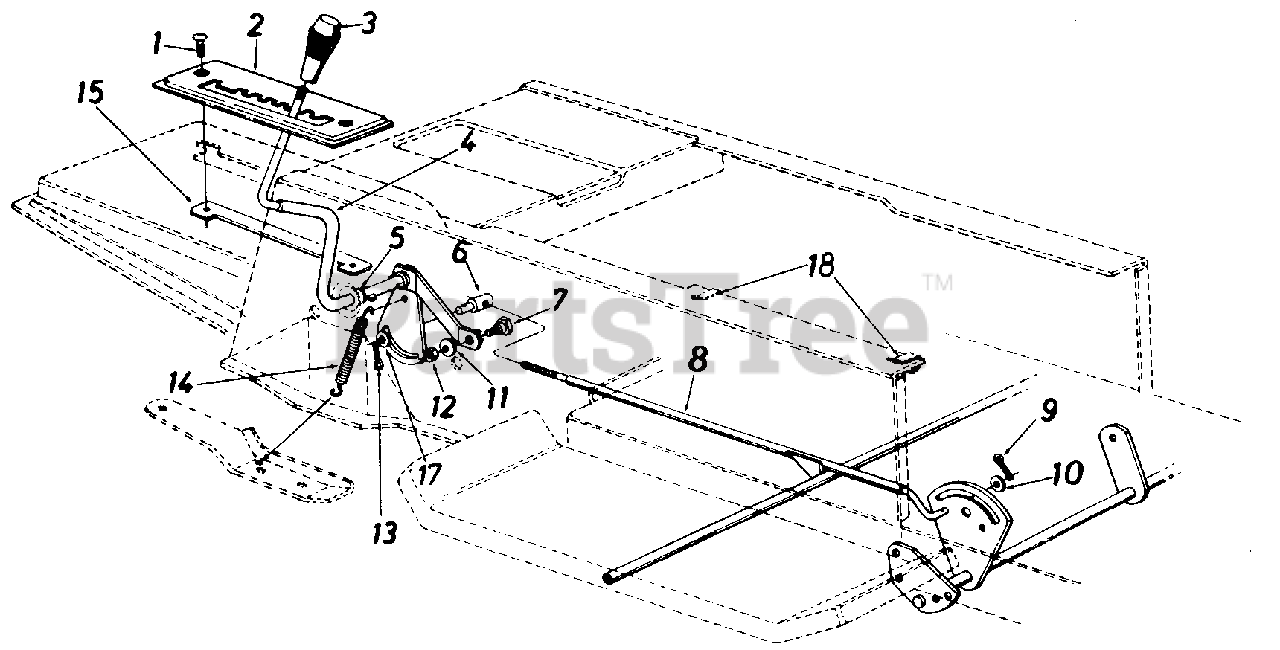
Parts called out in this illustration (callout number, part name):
1	Truss Mach. Scr. 1/4-20 x .75" Lg.
2	5-Speed Selector Plate
4	Speed Selector Cam Ass'y.
5	Flat Washer .53" I.D. x .93"
6	Ferrule 3/8-24 x .37" Dia.
7	Shoulder Bolt
8	Speed Control Rod Ass'y.
9	Cotter Pin 3/32" Dia. x .75"
10	Fl-Wash. .469" I.D. x .88"
11	L-Wash. 5/16" I.D.
12	Hex Nut 5/16-18 Thd.
13	Cotter Pin 3/32" Dia. x .75"
14	Spring .38" O.D. x 3.18" Lg.
15	Clamping Plate
17	Fl-Wash. .385" I.D. x .62"
18	Speed Clip
